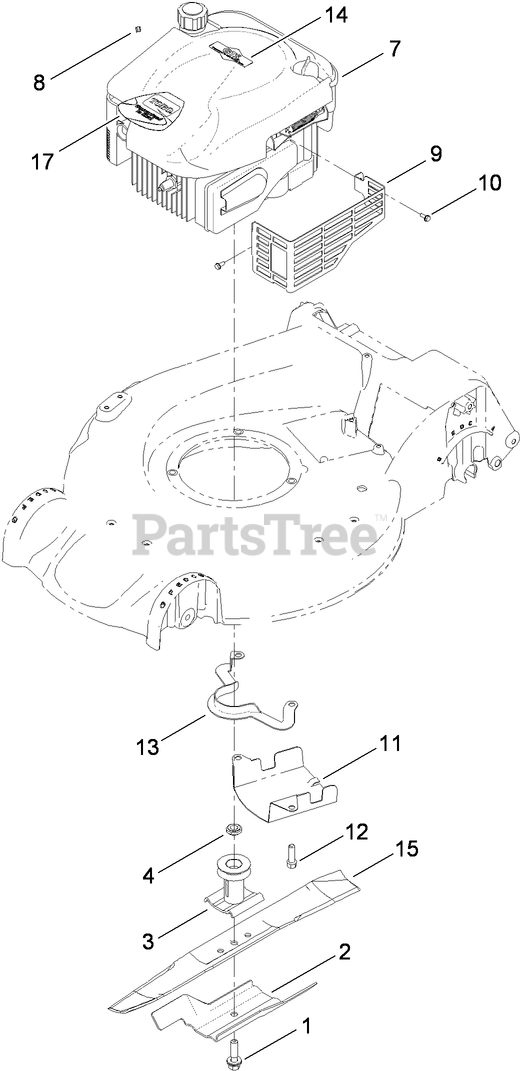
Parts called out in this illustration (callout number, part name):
2	ACCELERATOR-BLADE
3	DRIVER-BLADE
4	SPACER-DRIVER
8	STOP-ROPE
9	SHIELD-MUFFLER
10	SCREW-TAPTITE
11	SHIELD-GRASS
12	SCREW-TAPTITE
13	GUIDE-BELT
14	DECAL-RECOIL
17	DECAL-SHROUD
